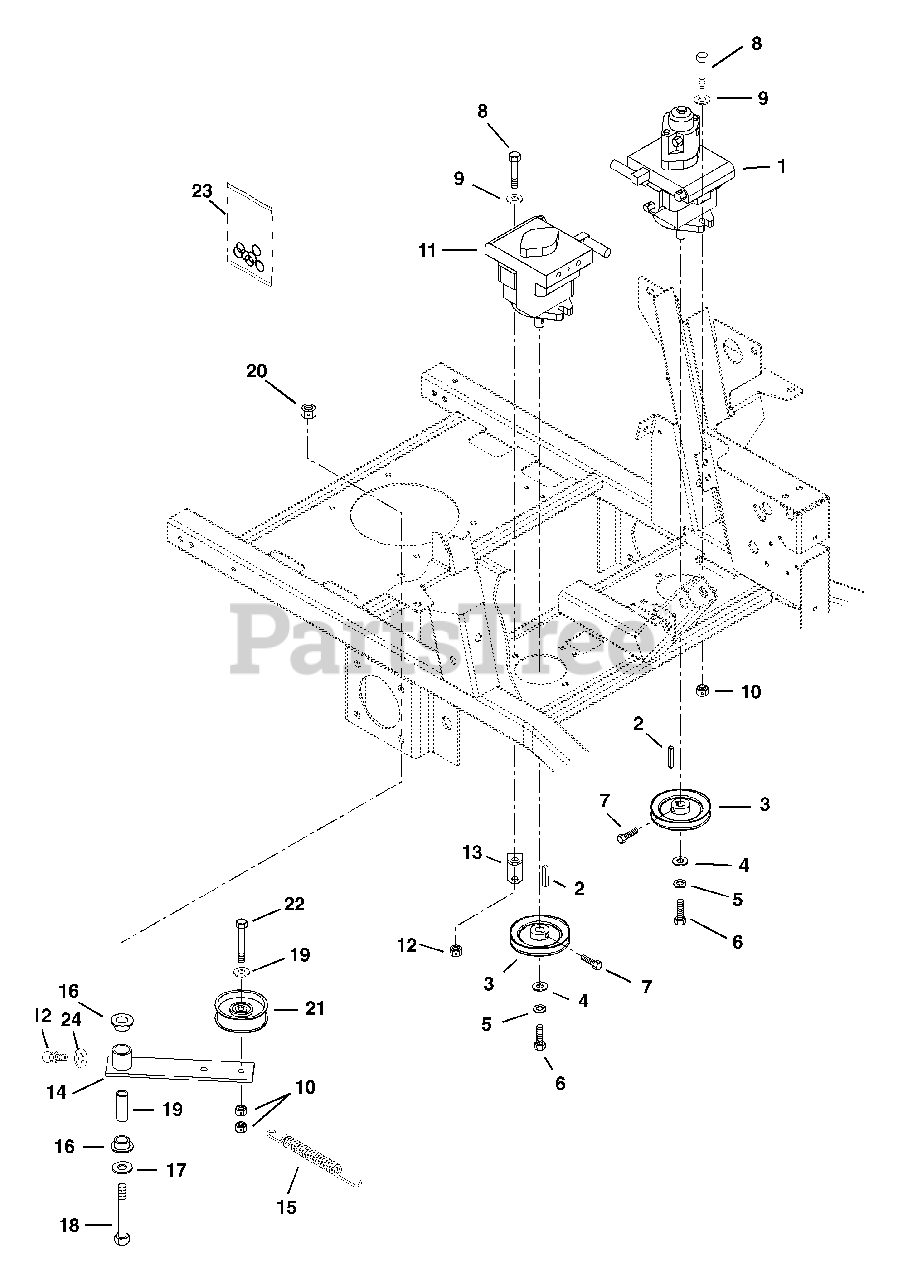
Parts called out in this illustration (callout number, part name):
1	Hydrostat BDP with Auxiliary
2	Key-Straight 5mm x 25mm x 5mm
3	Sheave 4.0 x .199
4	Washer-Flat-Steel .25 x 1.0 x .048
5	Washer-Locking .25 x .062
6	Bolt-Hex M6 x 1.0 x 12
7	Bolt-Hex .25 - 20 x .50 Grade 5
8	Bolt-Hex .38 - 16 x 1.25 Grade 5
9	Washer-Flat-Steel .390 x .75 x .125
10	Nut-Locking-Center .38-16
11	Variable-Displace Pump
12	Fitting-Lube .25 - 28 x .256
13	Anchor-Spring-Idler
14	Arm-Ground Drive Idler
15	Spring-Tension .120 x .845 x 6.500
16	Bushing-Flange .762 x 1.0 x .580 x 1.48
17	Washer-Flat-Steel .531 x 1.06 x .095
18	Bolt-Hex .50 - 13 x 3.00 Grade 5
19	Bushing-Steel .560 x .745 x 2.04
20	Nut-Locking-Center .50 - 13
21	Assembly-Idler Pulley
22	Bolt-Hex .38 - 16 x 2.25 Grade 5
23	Kit-Pump Seal
24	Washer-Flat-Steel .265 x .50 x .087
